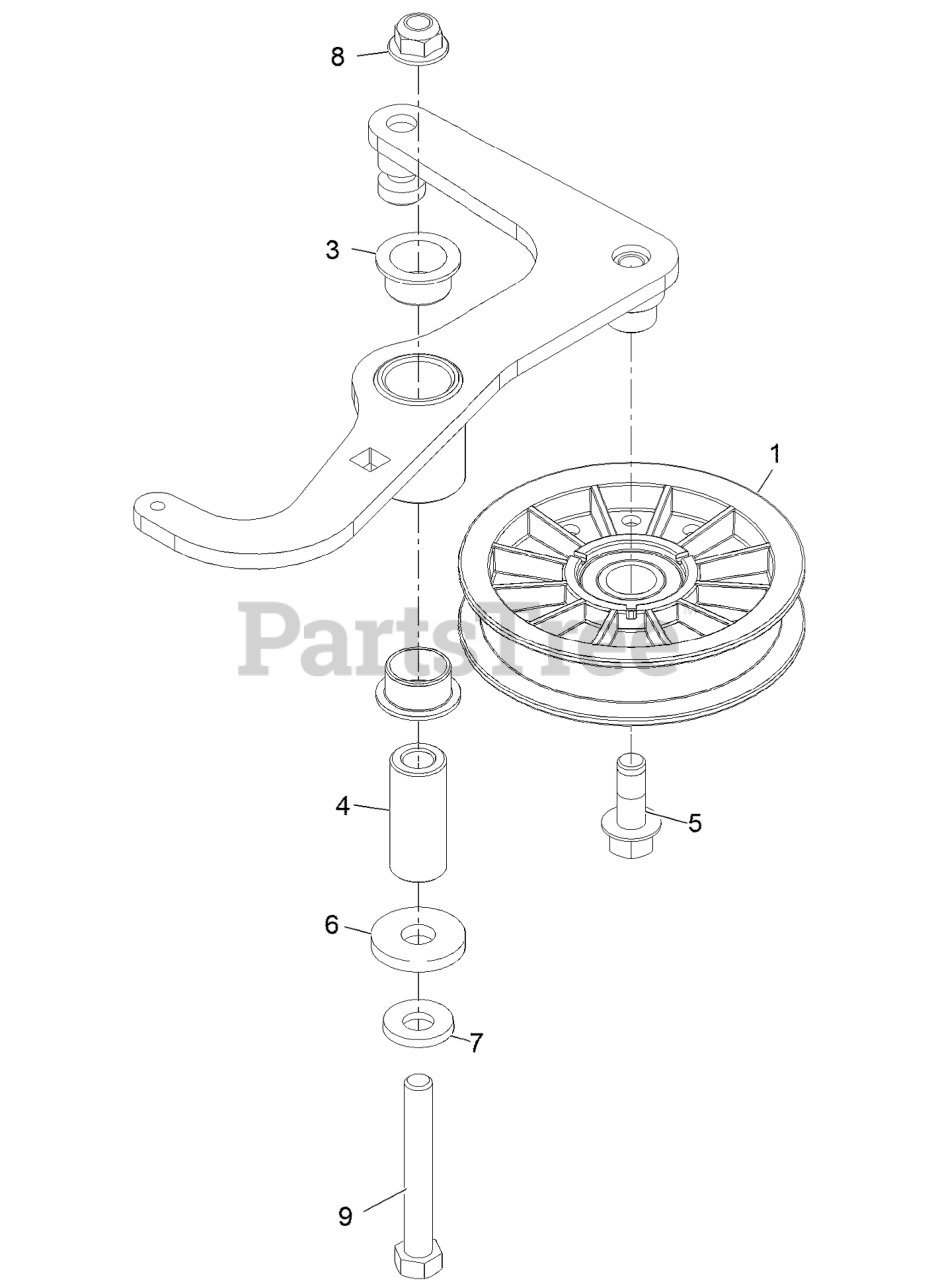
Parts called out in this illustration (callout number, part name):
1	PULLEY-IDLER, FLAT
3	BUSHING-FLANGE
4	SPACER, PIVOT
5	SCREW-HFH
7	WASHER-BELLEVILLE
8	NUT-HF, NI
9	SCREW-TAP
